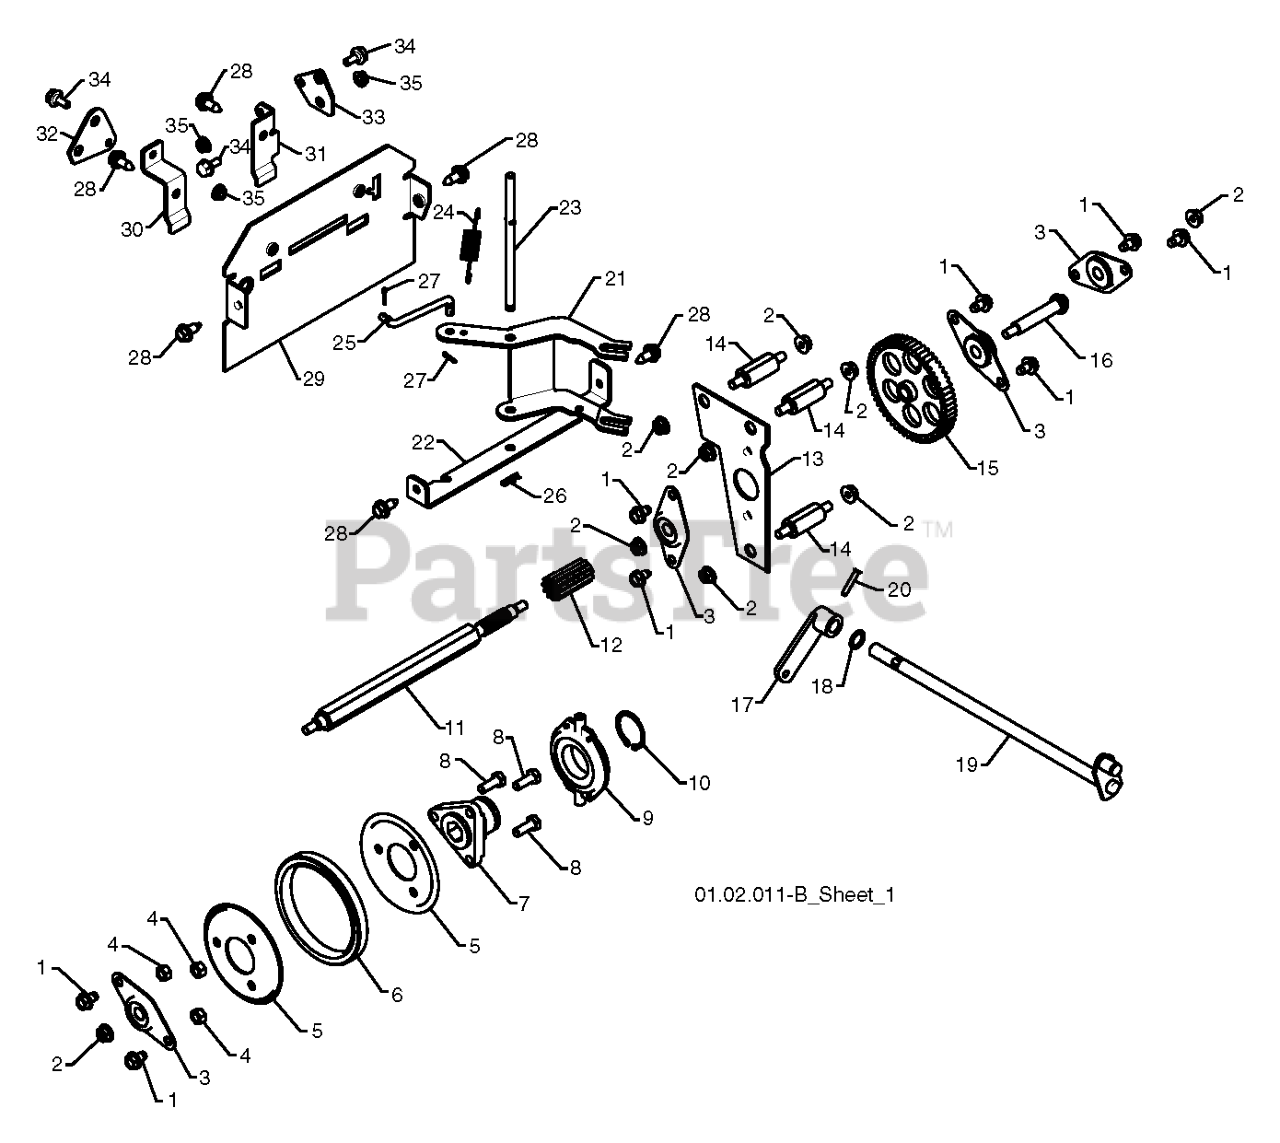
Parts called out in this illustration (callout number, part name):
1	Screw 5/16-18 x 1/2 Hex, Self Tapping 5/16-18 x 1/2
2	NUT.LOCK.5/16-18
3	BEARING, FLANGE
4	NUT.CENTERLOCK.5/16-
5	PLATE.RUBBER.WHEEL.BLACK
6	RING, RUBBER WHEEL
7	HUB, RUBBER WHEEL
8	BOLT
9	TRUNNION BEARING ASSY
10	RETAINING RING (2 2)(3 2)
11	SHAFT.HEX.LONG
12	GEAR, PINION
13	AUXILLARY PLATE
14	SPACER, PLATE
15	GEAR, INTERMEDIATE
16	SHAFT, AUXILIARY
17	ARM, AUGER CONTROL
18	THRUST WASHER
19	CONTROL.SHAFT.ASM
20	CLEVIS PIN
21	LEVER, SPEED CONTROL
22	BRACKET, PIVOT, SHIFT
23	PIN, PIVOT
24	SPRING, BIAS
25	LINK, SPEED CONTROL
26	RETAINER CLIP PM
27	RETAINER CLIP
28	BOLT.HEX.HD.WASHER.5/16-18X.75
29	PLATE.REAR.SNOW.PNT.ORANGE
30	RP BRACKET.SHIFTER.PLATE
31	BRACKET.CLUTCH.PLATE
32	RP PLATE.SHIFTER.
33	LATE.CLUTCH.
34	BOLT.SHOULDER.3/X.25
35	NUT.HEX.FLANGE.1/4
